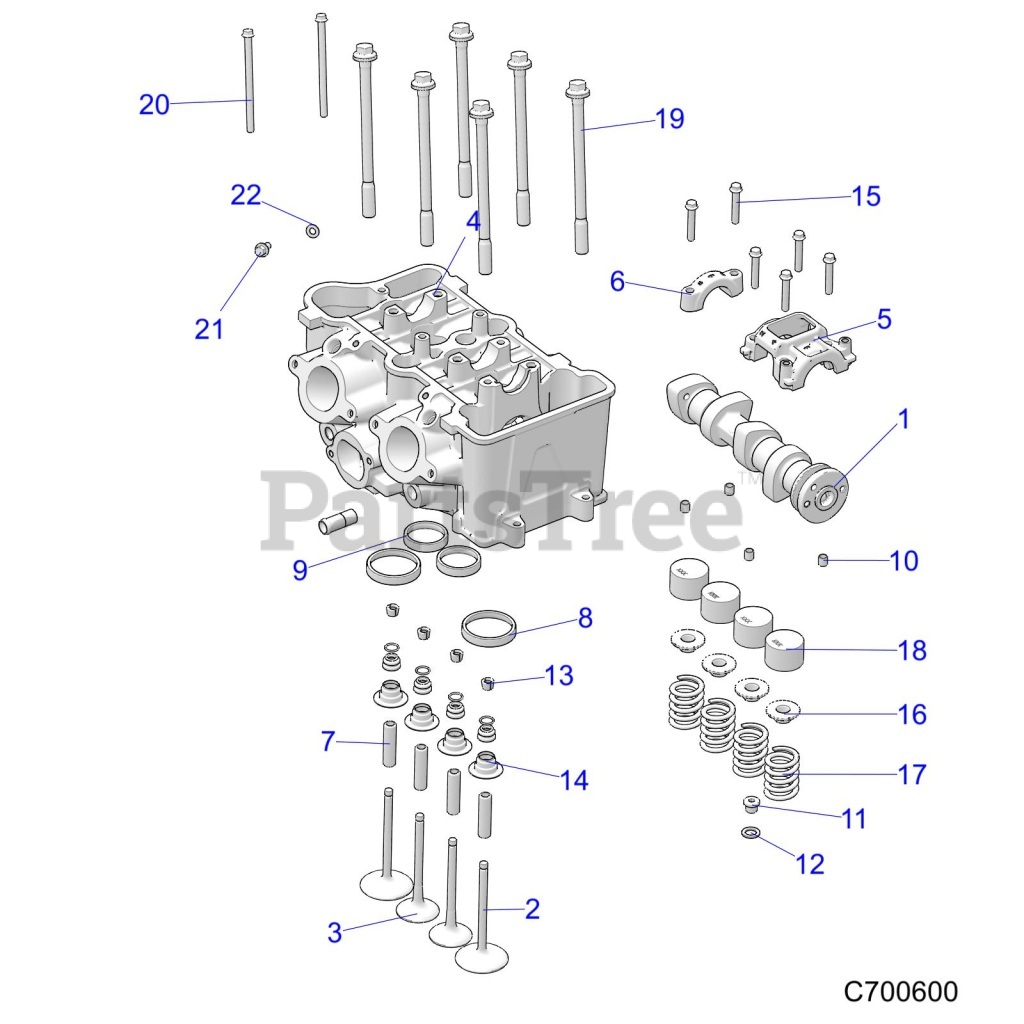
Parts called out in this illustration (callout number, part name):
1	ASM-CAMSHAFT,2CYL,SOHC
2	VALVE-INTAKE,47MM
3	VALVE-EXHAUST,38MM
4	ASM-HEAD,MACH,SOHC
4	HEAD-CYL,MACH,SOHC
5	CARRIER-CAMSHAFT,SOHC
6	CARRIER-CAMSHAFT,SOHC,PTO
7	GUIDE-VALVE,EXHAUST
8	SEAT-VALVE,INTAKE
9	SEAT-VALVE,EXHAUST
10	DWL-HOL,M8X8
11	PLUG-M10X1.0
12	WSHR-10.3X16X1.5 CU
13	KEEPER-VALVE
14	SEAL-VALVE STEM,SPRING SEAT
15	SCR-HXFL M6X1.0X35 10.9
16	RETAINER-VALVE SPRING
17	SPRING-VALVE
18	TAPPET, VALVE, GRADED, 4.400
18	TAPPET, VALVE, GRADED, 4.425
18	TAPPET, VALVE, GRADED, 4.450
18	TAPPET, VALVE, GRADED, 4.475
18	TAPPET, VALVE, GRADED, 4.500
18	TAPPET, VALVE, GRADED, 4.525
18	TAPPET, VALVE, GRADED, 4.550
18	TAPPET, VALVE, GRADED, 4.575
18	TAPPET, VALVE, GRADED, 4.600
18	TAPPET, VALVE, GRADED, 4.625
18	TAPPET, VALVE, GRADED, 4.650
18	TAPPET, VALVE, GRADED, 4.675
18	TAPPET, VALVE, GRADED, 4.700
18	TAPPET, VALVE, GRADED, 4.725
18	TAPPET, VALVE, GRADED, 4.750
18	TAPPET, VALVE, GRADED, 4.775
18	TAPPET, VALVE, GRADED, 4.800
18	TAPPET, VALVE, GRADED, 4.825
18	TAPPET, VALVE, GRADED, 4.850
18	TAPPET, VALVE, GRADED, 4.875
18	TAPPET, VALVE, GRADED, 4.900
18	TAPPET, VALVE, GRADED, 4.925
18	TAPPET, VALVE, GRADED, 4.950
18	TAPPET, VALVE, GRADED, 4.975
18	TAPPET, VALVE, GRADED, 5.000
18	TAPPET, VALVE, GRADED, 5.025
18	TAPPET, VALVE, GRADED, 5.050
18	TAPPET, VALVE, GRADED, 5.075
18	TAPPET, VALVE, GRADED, 5.100
18	TAPPET, VALVE, GRADED, 5.125
18	TAPPET, VALVE, GRADED, 5.150
18	TAPPET, VALVE, GRADED, 5.175
18	TAPPET, VALVE, GRADED, 5.200
18	TAPPET, VALVE, GRADED, 5.225
18	TAPPET, VALVE, GRADED, 5.250
18	TAPPET, VALVE, GRADED, 5.275
18	TAPPET, VALVE, GRADED, 5.300
18	TAPPET, VALVE, GRADED, 5.325
18	TAPPET, VALVE, GRADED, 5.350
18	TAPPET, VALVE, GRADED, 5.375
18	TAPPET, VALVE, GRADED, 5.400
18	TAPPET, VALVE, GRADED, 5.425
18	TAPPET, VALVE, GRADED, 5.450
19	SCR-HXFL,M11X1.25X150 10.9 SEM
21	SCR-M6X1.0X13,SL/HX/FL-Z,BLEED
22	WASHER-FLAT,6.15X12X1MM-AL
